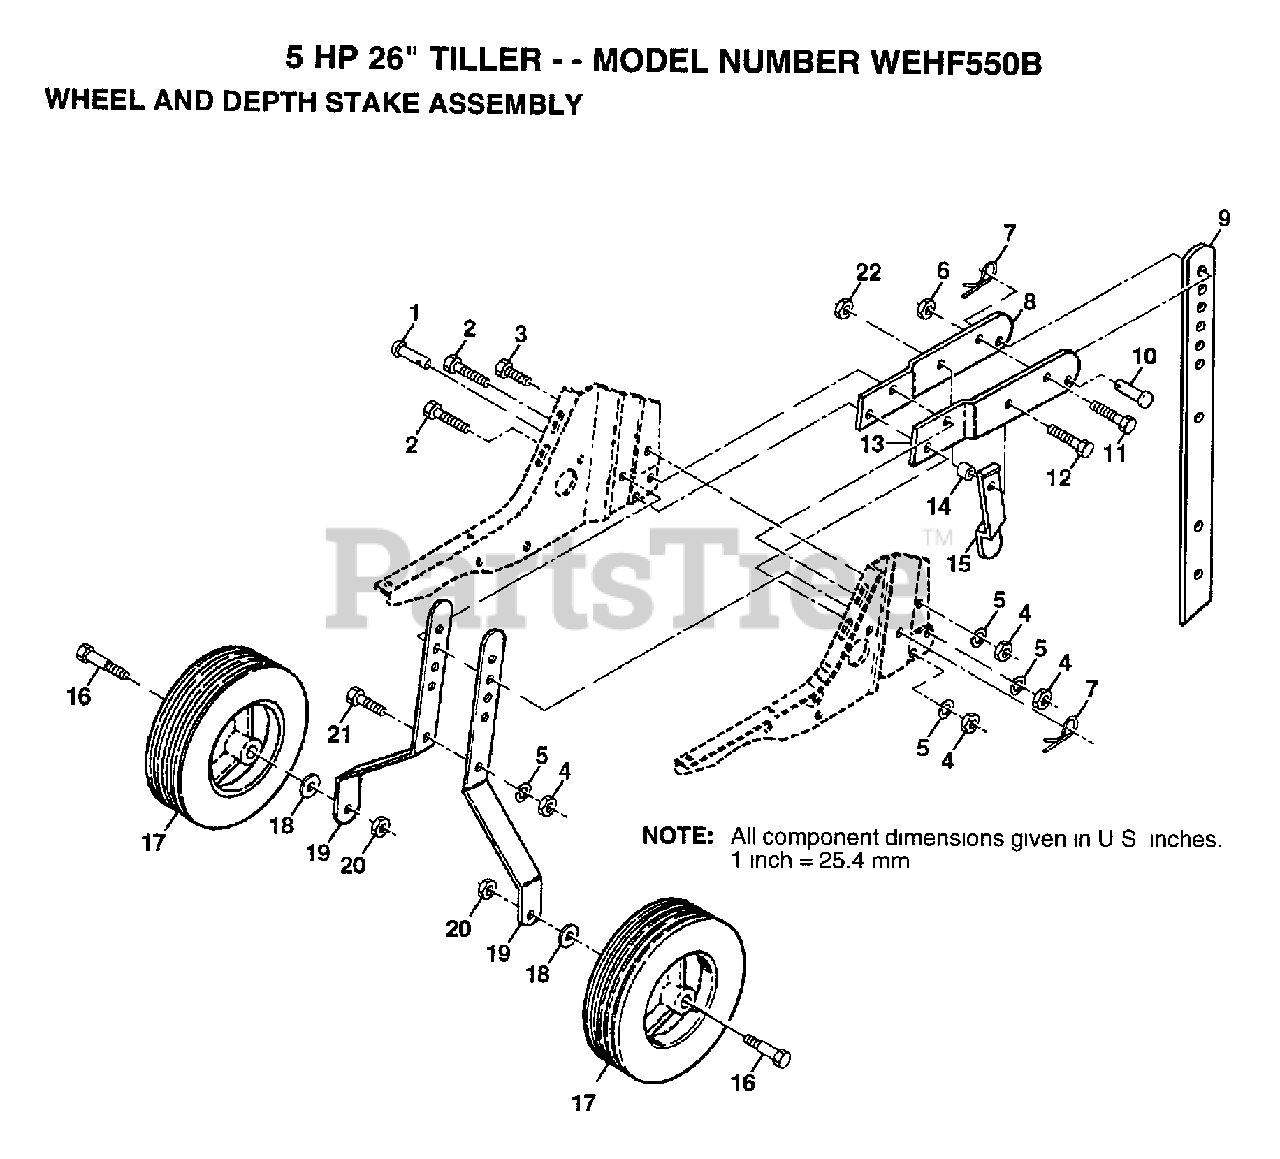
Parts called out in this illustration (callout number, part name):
1	DRILLED RIVET RT
3	BOLT
4	NUT.HEX.5/16-18
5	LOCKWASHER
6	NUT
7	SPRING.RETAINER
8	SUPPORT STAKE RH
11	BOLT
12	BOLT.HEX.5/16-1.5
13	SUPPORT STAKE LH
14	WASHER
15	STAKE SPRING TI
16	BOLT SHOULDER
17	WHEEL.8X1.75.YELL
18	WASHER
19	BRACKET.WHL.PNT.
22	NUT
